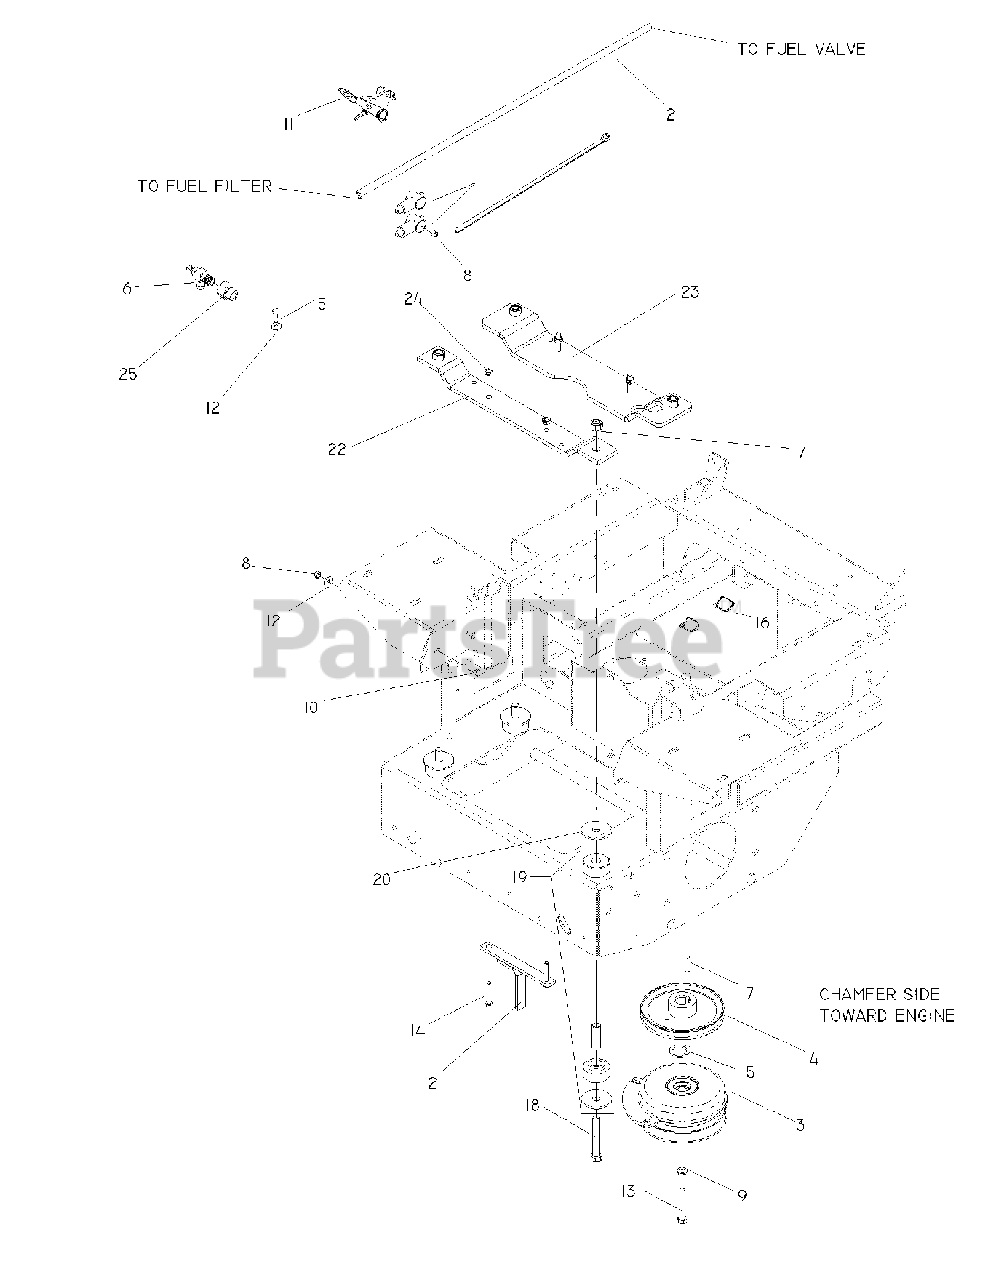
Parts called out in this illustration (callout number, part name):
1	INSULATOR
2	FUEL LINE 24"
3	CLUTCH-200 FT LB(RPLS 5218-102
5	HEX HEAD SCREW M6 X 1 X 20
6	OIL DRAIN ADAP.(HONDA)
7	KEY, 1/4 SQ X 1 1/4
8	NUT 1/4-20 NYLOC
9	WASHER 7/16 LOCK
10	HCS 1/4 X 1
11	CABLE CHOKE
12	WASHER 1/4 FLAT
13	BOLT 7/16F X 2 1/2
14	HCS 5/16C X 1 3/4
15	BUSHING, 10GA MACHINERY
16	TIE, PLASTIC
17	NUT 1/2-13 HEX NYLOC ZD
18	HCS 1/2C X 3 1/4
19	ISOLATORS
20	ISOLATOR WASHER
21	CLUTCH TIE DOWN
22	STRAP, ISO, REAR
23	MOUNT, ENGINE - BLACK
24	NUT 5/16C CENTERLOCK
